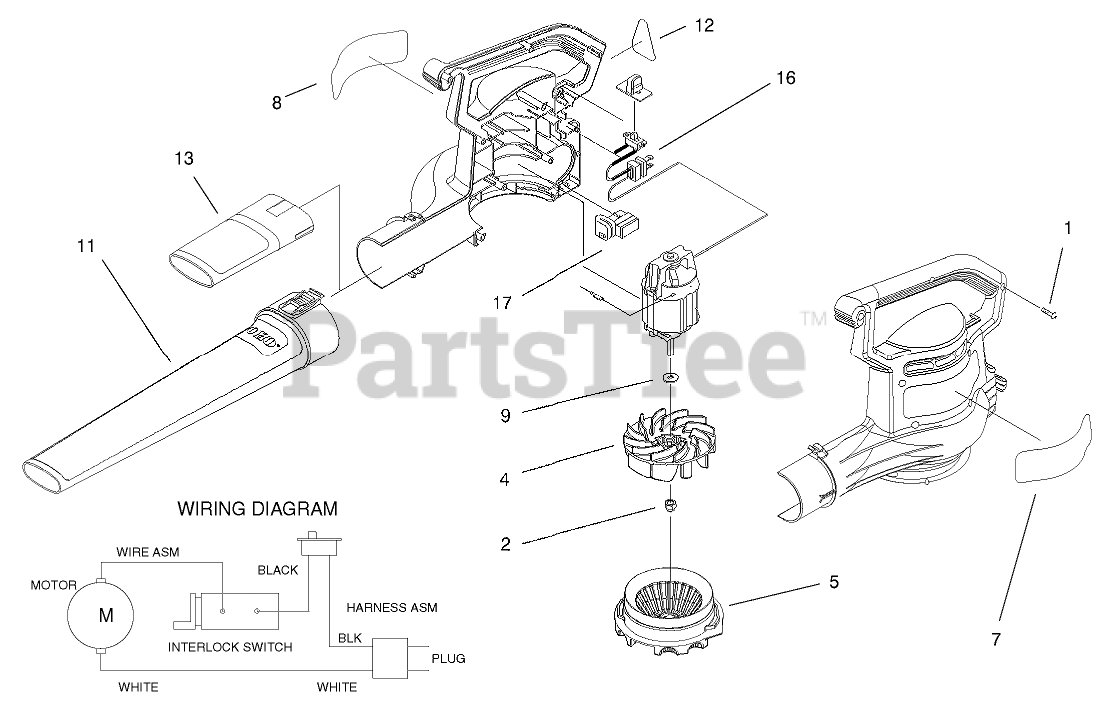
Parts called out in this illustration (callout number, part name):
1	SCREW-PPH
2	NUT-HEX
4	IMPELLER - BLOWER
5	INLET COVER & DECAL ASM
7	DECAL-LOGO
8	DECAL - WARNING
9	WASHER
11	TUBE-BLOWER LONG
12	DECAL - INFORMATION
13	INSERT - TUBE
16	WIRE HARNESS
17	SWITCH - INTERLOCK
